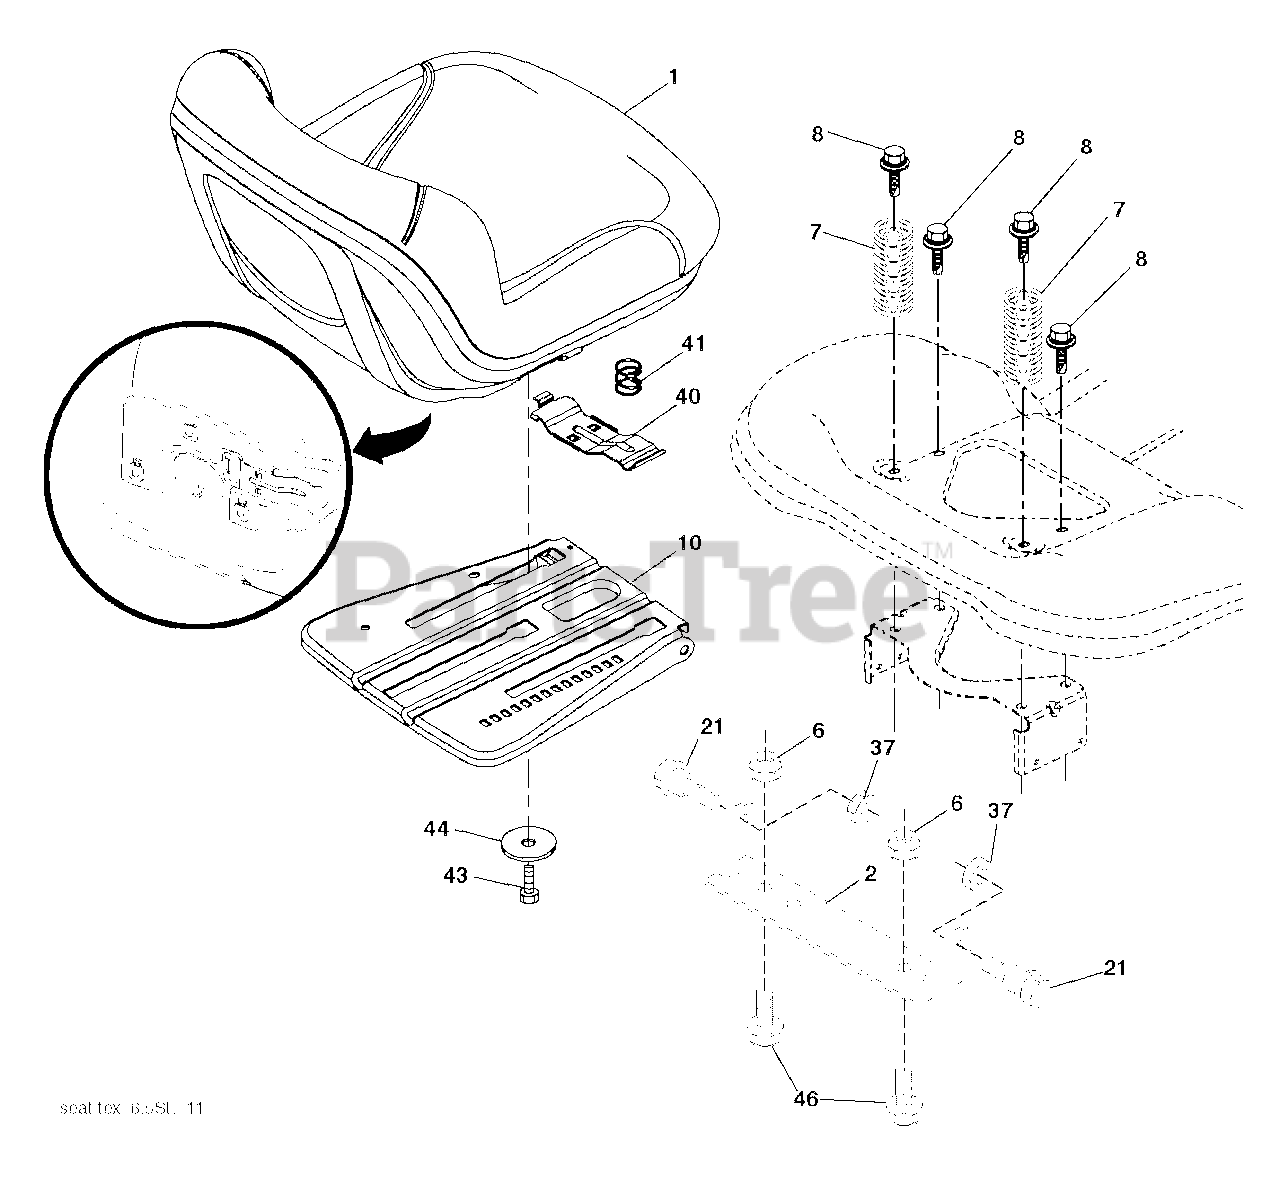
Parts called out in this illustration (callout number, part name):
1	SEAT.TH150.MS498.GRY.HUSQ.TEX
2	BRKT.PIVOT.FENDER
6	NUT
7	SPRING.COMPRESSION.SEAT.BLACK
8	BOLT, 5/16-18 X 1 3/4
10	PAN.ASM.SEAT.3PT
21	BOLT.5/16-18X5/8.SHOULDER
37	NUT.71038.31-18.HEX.NYLOCK
40	HANDLE.SLIDE.SEAT.TEX.GREY
41	SPRING.LATCH.SEAT.TEX
44	WASHER 13/32 X 2-3/8 X 12GA
46	BOLT.3/8-16X1;1.25OD.WSHR.SEMS
